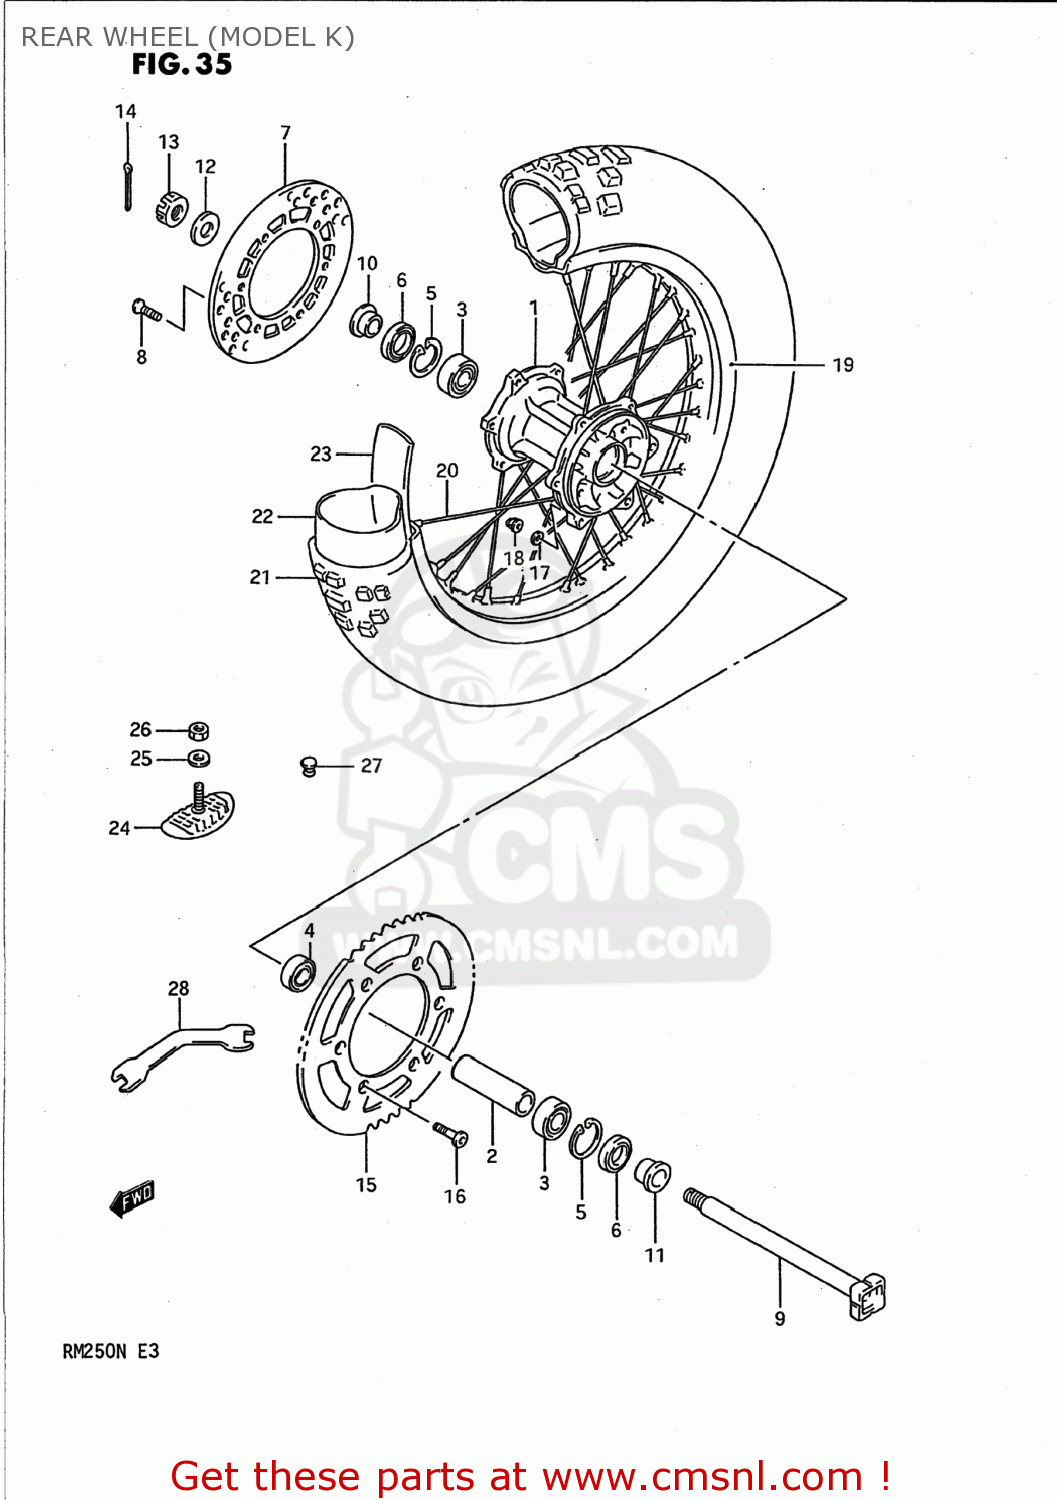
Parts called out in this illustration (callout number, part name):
1	HUB,RR
2	SPACER,RR HUB BEARING
3	BEARING WHEEL REAR(20X47X14)
4	BALL BEARING
5	CIRCLIP,14MM
6	OIL SEAL
7	DISC,REAR BRAKE
8	SCREW
9	AXLE,RR
10	SPACER,RR AXLE,R
11	SPACER,RR AXLE,L
12	WASHER (19X32X3.2)
13	NUT 18MM
14	PIN,COTTER
15	SPROCKET,REAR
16	SCREW(8X33.5)
17	WASHER
18	NUT
19	RIM,REAR WHEEL (2.15X18)(A
20	SPOKE ASSY,RR WHEEL
21	TIRE,REAR
22	TUBE,INNER
23	PROTECTOR,WHEEL,INNER
24	STOPPER,BEAD
25	WASHER
26	NUT 8MM
27	CAP(OD:12)
28	SPANNER,OPEN
